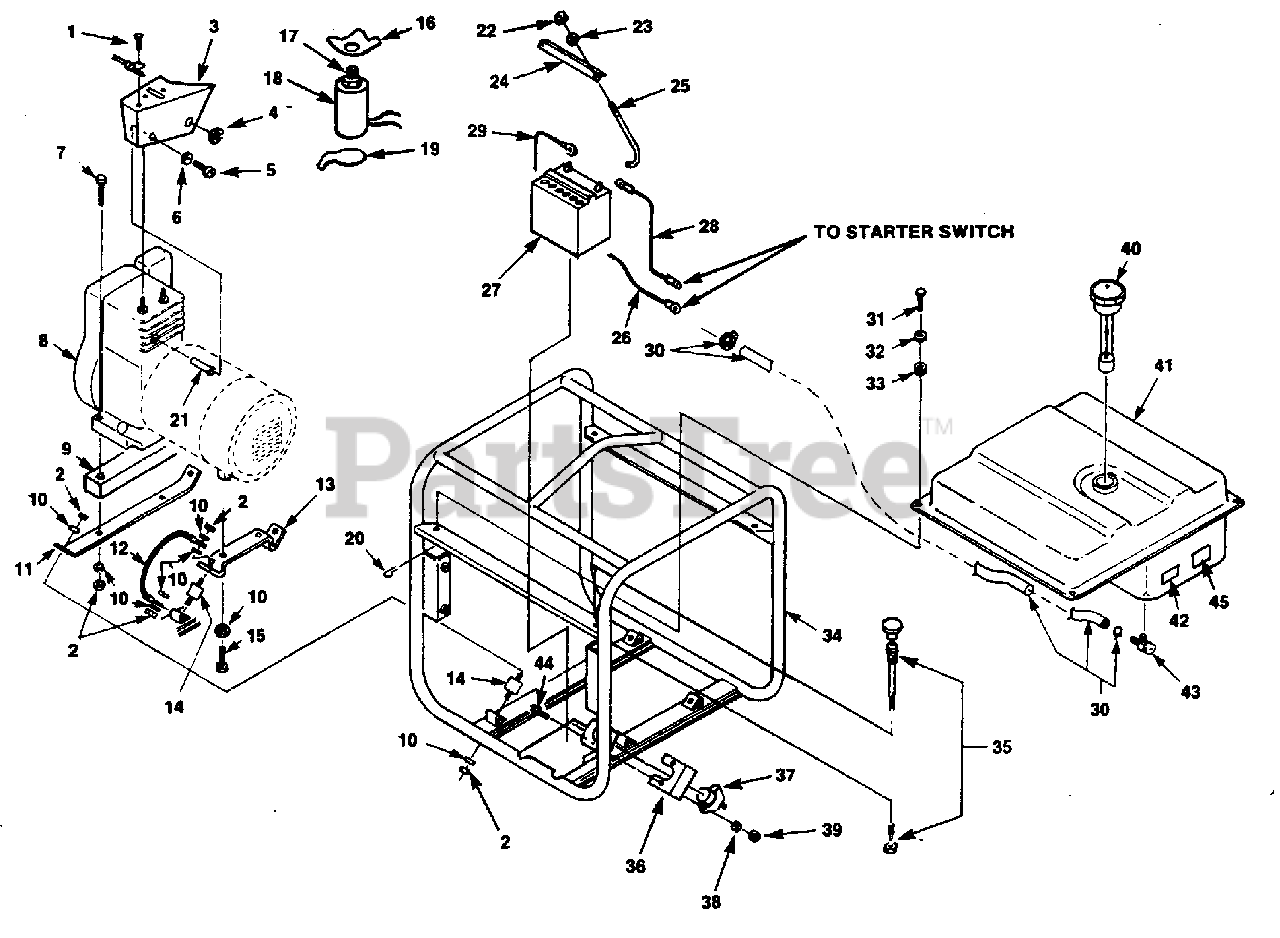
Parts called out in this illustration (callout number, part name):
1	SCREW- Tap Pan Hd. (#8-18 x 3/8)
2	NUT- Hex 5/16-18
3	DEFLECTOR- Air
4	GROMMET
5	SCREW- Hex 6mm x 40mm
6	WASHER- 1/4
7	SCREW- Cap Hex Hd. (5/16-18 x 1 1/4)
8	ENGINE- 11 H.P.
10	WASHER- Int. Lock 5/16
11	SUPPORT- Engine
12	GROUND- Strap
13	SUPPORT- Generator
14	VIBRATOR ISOLATOR
15	SCREW- Thread Forming (5/16-18 x 1)
16	BRACKET- Magnet
17	NUT- Hex 1/4-28
18	ELECTROMAGNET
19	ARM- Throttle
20	PIN- Cotter
22	NUT- Hex #10
23	WASHER- Lock #10
24	STRAP- Battery
25	BOLT- Battery
26	LEAD- Electrical
28	CABLE- Battery (Red)
29	CABLE- Battery (Black)
30	FUEL LINE ASSEMBLY
31	PIN- Clevis
32	WASHER- Flat
33	GROMMET- Isolator
34	ROLL CAGE
35	CABLE- Choke
36	COVER-Switch
37	SWITCH- Starter
38	WASHER-Lock 1/4
39	NUT- Hex 1/4-20
40	CAP-Fuel
41	TANK- Fuel
42	DECAL- Fuel Valve
43	FUEL VALVE
44	SCREW- 1/4-20 x 1/2
45	DECAL- Caution
